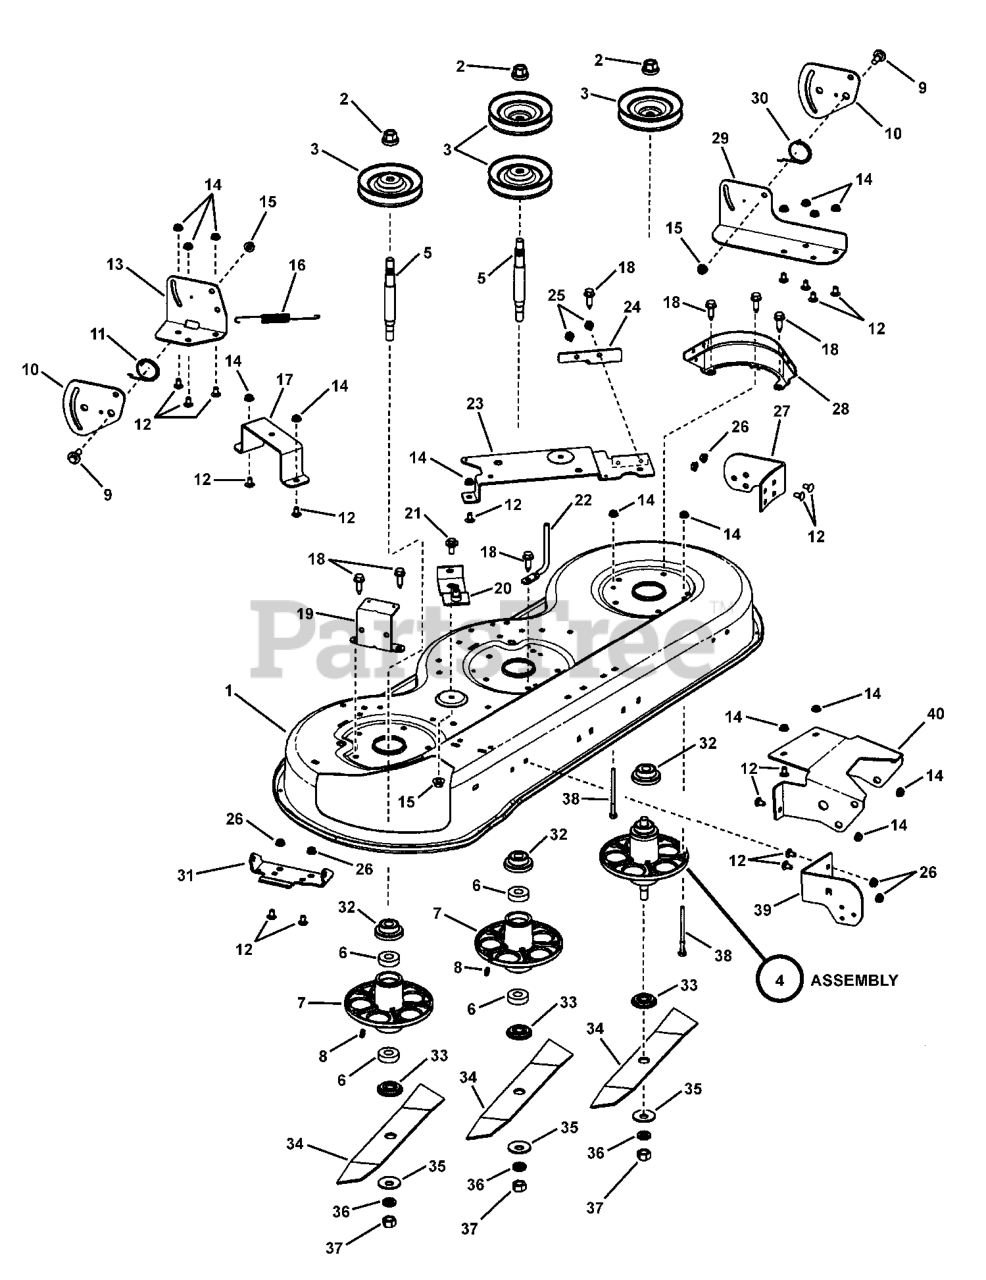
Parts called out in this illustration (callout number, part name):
1	MOWER DECK HOUSING, 46"
2	NUT-NYLOCK RING - PULLEY 9/16-18
3	S.S. PULLEY 46"
4	JACKSHAFT HOUSING ASSY
5	SHAFT, SPLINED
6	BALL BEARING, JACKSHAFT
7	JACKSHAFT HOUSING
8	FITTING - LUBRICATION
9	SHOULDER BOLT, 3/8-16X1.06
10	PLATE SUSPENSION
11	SPRING, TORSION RH
12	BOLT CARRIAGE, 5/16-18 X .62
13	BRACKET, RIGHT REAR
14	HEX NUT, 5/16-18 FLANGE SER YZ
15	NUT, HEX FLANGE, 3/8-16 NC
17	BRACKET, BELL CRANK
18	HHST, 3/8-16X1.25
19	BRACKET, COVER
20	ASSY- IDLER ARM, 46", RH
21	SHOULDER BOLT, 0.75 X 0.60 X 3/8-16
22	GUIDE, BELT
23	BRACKET, BRAKE MTG 46
24	BRACKET, BRAKE PLATE
25	CAPSCREW, 5/16-18
26	NUT, HEX FLANGE LOCK, 5/16-18 NC
27	BRACKET, LEFT GAUGE WHEEL
28	BRACKET, PULLEY COVER
29	BRACKET, LIFTER LH
30	SPRING, TORSION RH
31	BRACKET, HINGE
32	SPACER, PULLEY
33	BLADE ADAPTER
35	WASHER, BELLEVILLE 1.0 X .625 X .200
36	WASHER, HARDENED 1.0OD X .625ID X .188
37	NUT, BLADE, 9/16-18 ZINC PLATE YELLOW CHROMATE
38	GUIDE, SCREW (5/16-18)
39	BRACKET, RIGHT GAUGE WHEEL
40	BRACKET, FRONT DECK
